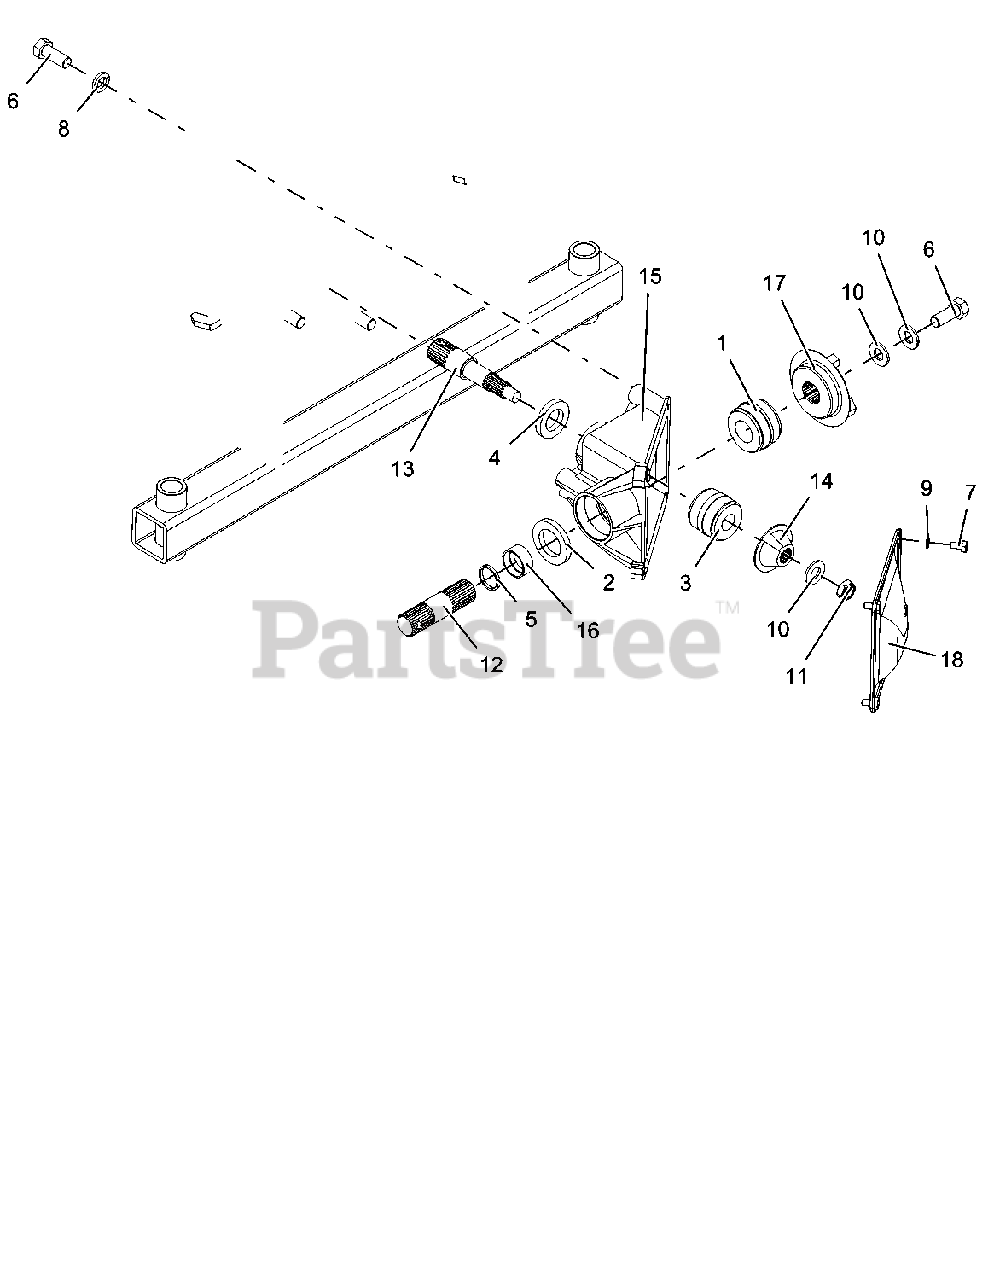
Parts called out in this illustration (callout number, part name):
1	BRG-ASM 1.000X1.980X1.243
2	SEAL 1.250X1.983X.250
3	BRG-ASM .75X1.781X1.499
4	SEAL 1.000X1.690X.250
5	RG-RTNG EXT 1.106X.95
6	BLT,HEX .50-13X1.25 G5ZC120
7	BLT,HEX .25-20X.50 G5ZC120
8	WSHR,LK-SPRG .50X.125 ZC120
9	WSHR, LK-SPRG .25X.062 ZC120
10	WSHR,FL-STL.531X1.06X.095ZC120
11	NUT, LK-NYL-JAM .50-20 ZC120
12	SHFT,DRIVE
14	GR,BEVEL
15	CSTG,GEAR BOX
16	BUSH F 1.00X1.25X1.25 ST
17	GR,BEVEL
18	CVR,GEAR HOUSING
